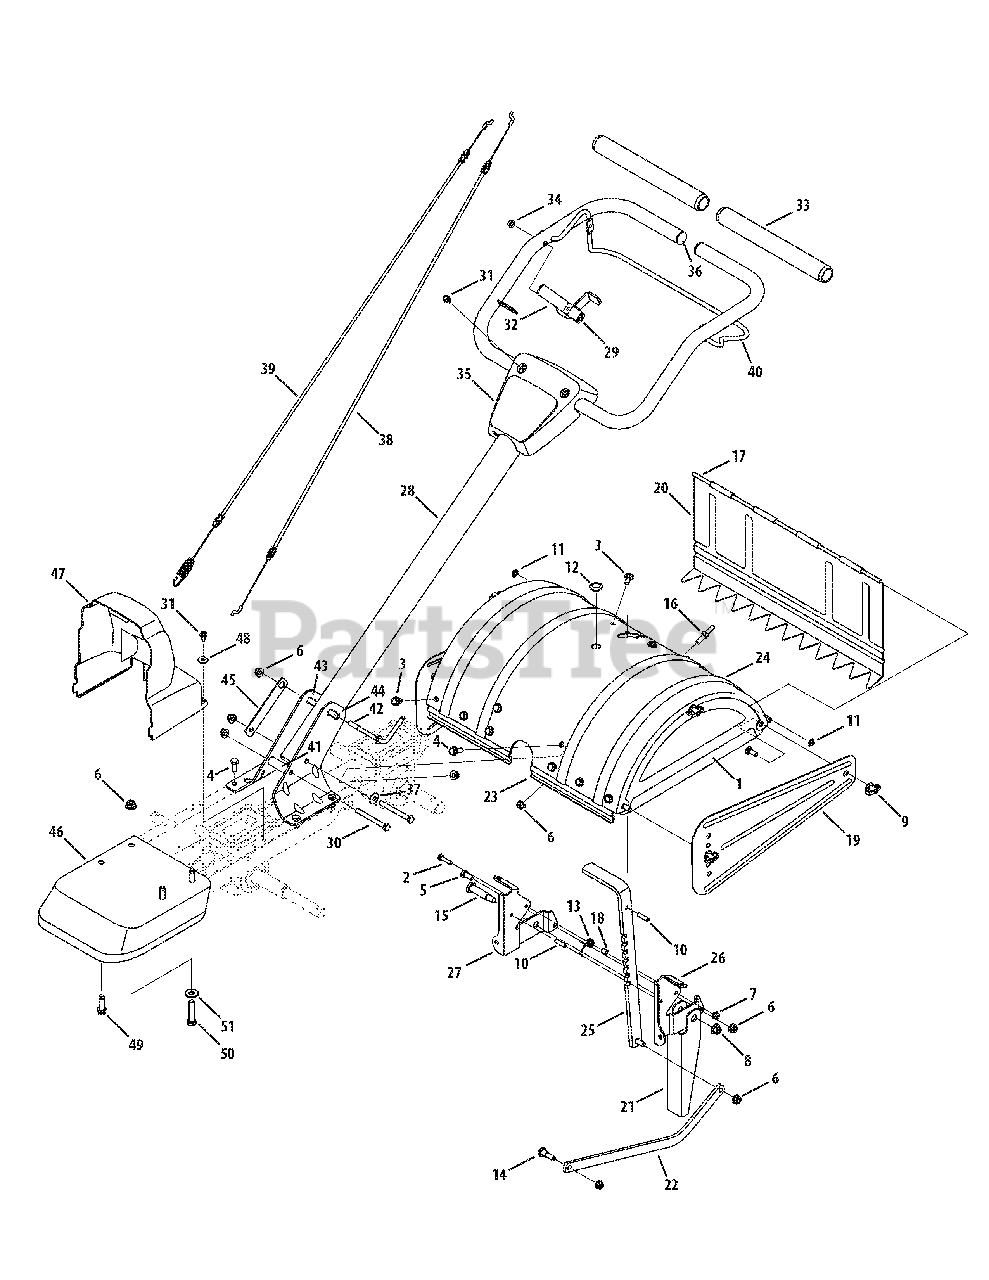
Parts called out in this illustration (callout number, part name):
1	End Cover Assembly
2	Hex Head Screw, 1/4-20 x 1
3	Hex Head Screw, 5/16-18 x .625
4	Hex Head Screw, 5/16-18 x .875
5	Hex Head Screw, 5/16-18 x .75
6	Nylon Hex Lock Nut, 5/16-18
7	Nylon Hex Lock Nut, 1/4-20
8	Flange Lock Nut, 3/8-16
9	Wing Nut, 5/16-18
10	Spirol Pin
11	Cap Nut, 1/4 Rod
12	Hole Plug
13	Torsion Spring
14	Shoulder Screw, .405 x .435 5/16-18
15	Shoulder Screw, .498 x 1.635
16	Stop Screw
17	Tiller Flap Rod
18	Spacer
19	Side Shield
20	Rear Tine Shield
21	Reverse Stop Arm
23	Tine Shield Mounting Bracket
24	Tine Shield
25	Adjustable Depth Bar
26	Tail Bracket, LH
27	Tail Bracket, RH
28	Upper Handle Assembly
29	Reverse Handle Assembly
30	Hex Head Screw, 5/16-18 x 3.00
31	Self-Tapping Screw, 1/4-20 x 1/2
32	Reverse Handle Grip
33	Foam Handle Grip
34	Cap Nut, .3125 dia.
35	Handle Cover
36	Plug End
37	Bell Washer, .340 x .872 x .060
38	Reverse Cable
39	Forward Cable
40	Clutch Bail
41	Spacer, .322 x .625 x 2.00
42	Handle Crank
43	Handle Bracket, RH
44	Handle Bracket, LH
45	Retainer Nut Bracket
46	Front Bumper
47	Belt Cover
48	Flat Washer, .28 x .74 x .063
49	SEMS Screw, 3/8-16
50	Hex Head Screw, 5/16-18 x 1.50
51	Bell Washer, .827 x .331 x .098
